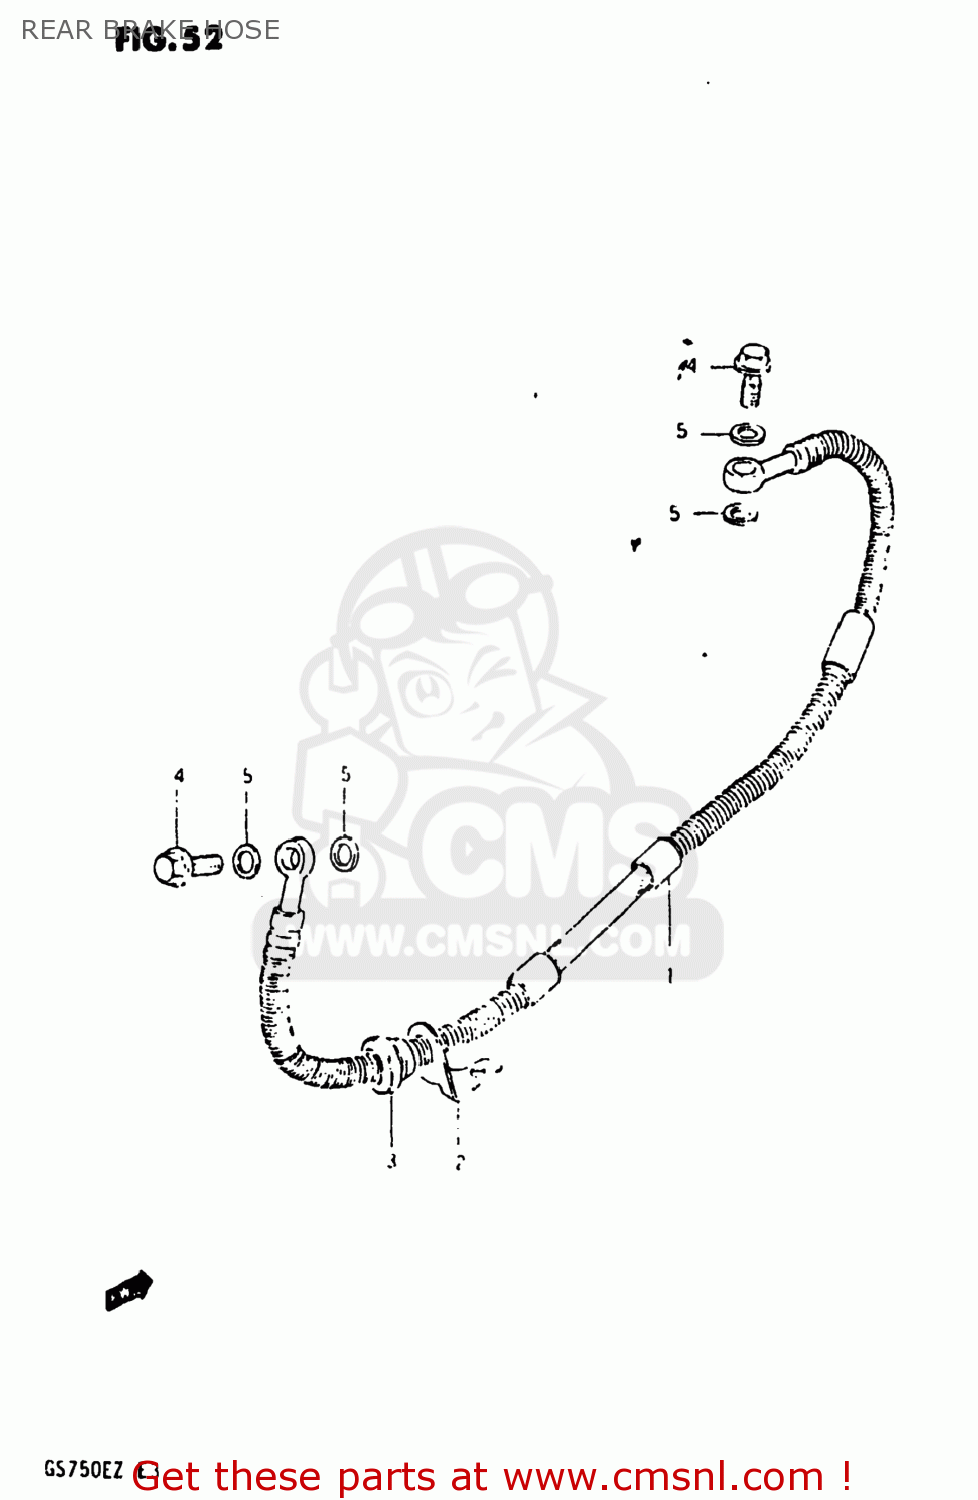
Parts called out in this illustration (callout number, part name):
1	HOSE,REAR BRAKE
2	GUIDE,BRAKE HOSE
3	GROMMET,BRAKE HOSE GUIDE
4	BOLT,UNION
5	WASHER
